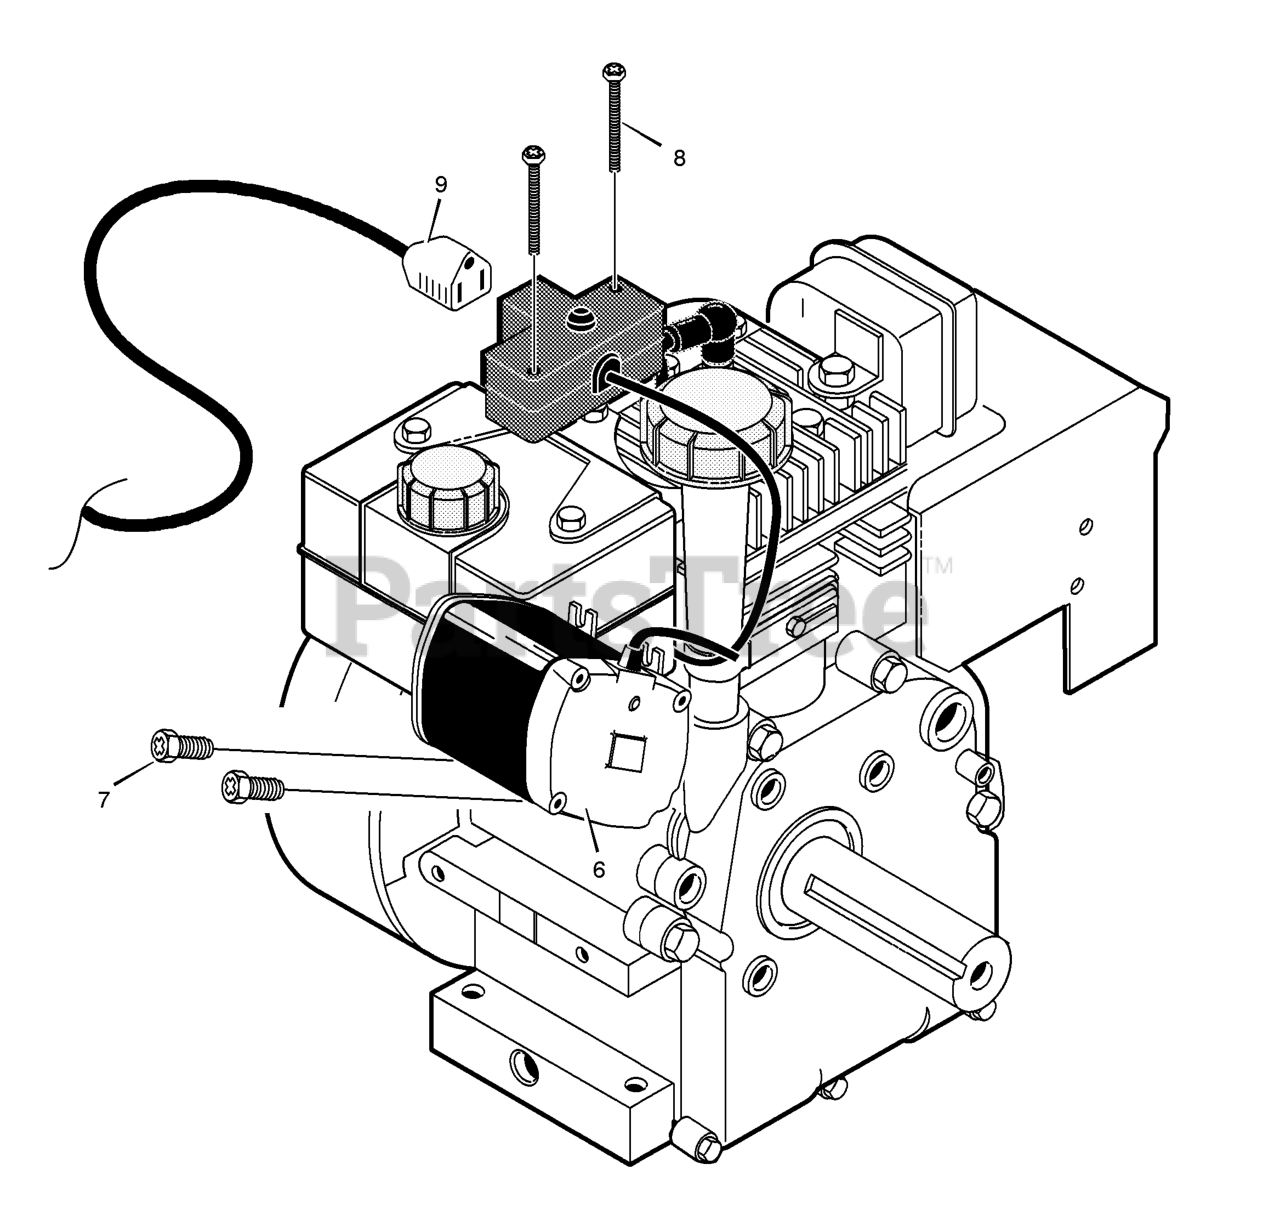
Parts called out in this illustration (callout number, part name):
6	MOTOR, STARTER
8	SCREW
9	CORD, Electric, 10FT. 110V
